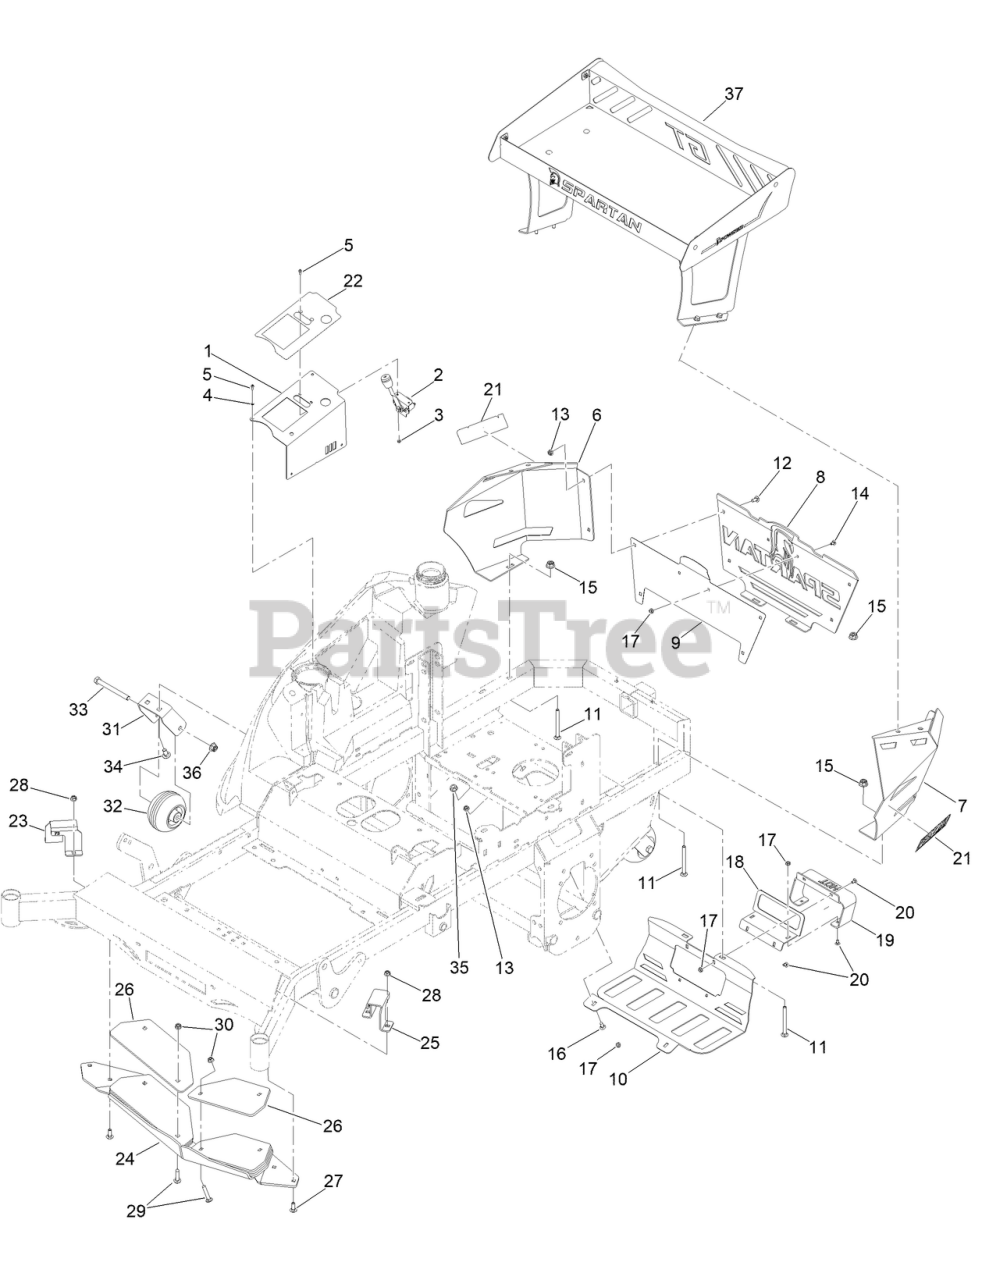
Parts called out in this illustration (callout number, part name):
1	KGZ EFI CONTROL PANEL BRACKET NEXCON
2	KAWASAKI EFI THROTTLE
3	NUT-LOCK
4	#10 SPLIT LOCKWASHER 18-8 SS
5	10-24 X 1/2 SOCKET C/S 18-8 SS
6	KGZ ENGN COWLING RT PAINTED
7	KGZ ENGN COWLING LT PAINTED
8	KGZ ENGN COWLING CNTR PAINTED
9	KGZ ENGN COWLING CTR BACKER PLATE PAINT
10	MUFFLER GUARD [BLK-TXT]
11	3/8-16 X 4 CARRIAGE BOLT ZINC
12	BOLT-CARR
14	SCREW-CARR
15	3/8-16 NYLON INSERT FLANGE L/NUT YZ
16	BOLT-CARR
17	1/4-20 HEX FLANGE NUT W/SERR ZINC
18	DUAL EXHAUST TIP BOTTOM BRKT BLACK
19	2022 KGZ DUAL EXHST TIP TOP BRKTORANGE
20	SCREW-CARR
21	2022 KGZ ENGN COWLING DECAL
22	DECAL-CONSOLE
23	2023 COUNTER WEIGHT TOP MOUNT BRK 72
24	2023 COUNTER WEIGHT RT/SRT BOTTOM MOUNT
25	2023 COUNTER WEIGHT TOP MOUNT BRK 73
26	2023 COUNTER WEIGHT PLATE
27	3/8-16 X 1 CARRIAGE BOLT YZ GR.8
29	SCREW-CARR
30	3/8-16 HEX FLANGE NUT W/SERR ZINC YELLOW
31	MWR STABILIZER MTG BRKT BLACK
32	MWR ANTI-SCALP WHL W/O GREASE FITTING
33	SCREW-HH
34	SCREW-CARR
35	NUT-HF
36	NUT-LOCK
37	2022 KGZ BLACK RR BASKET
